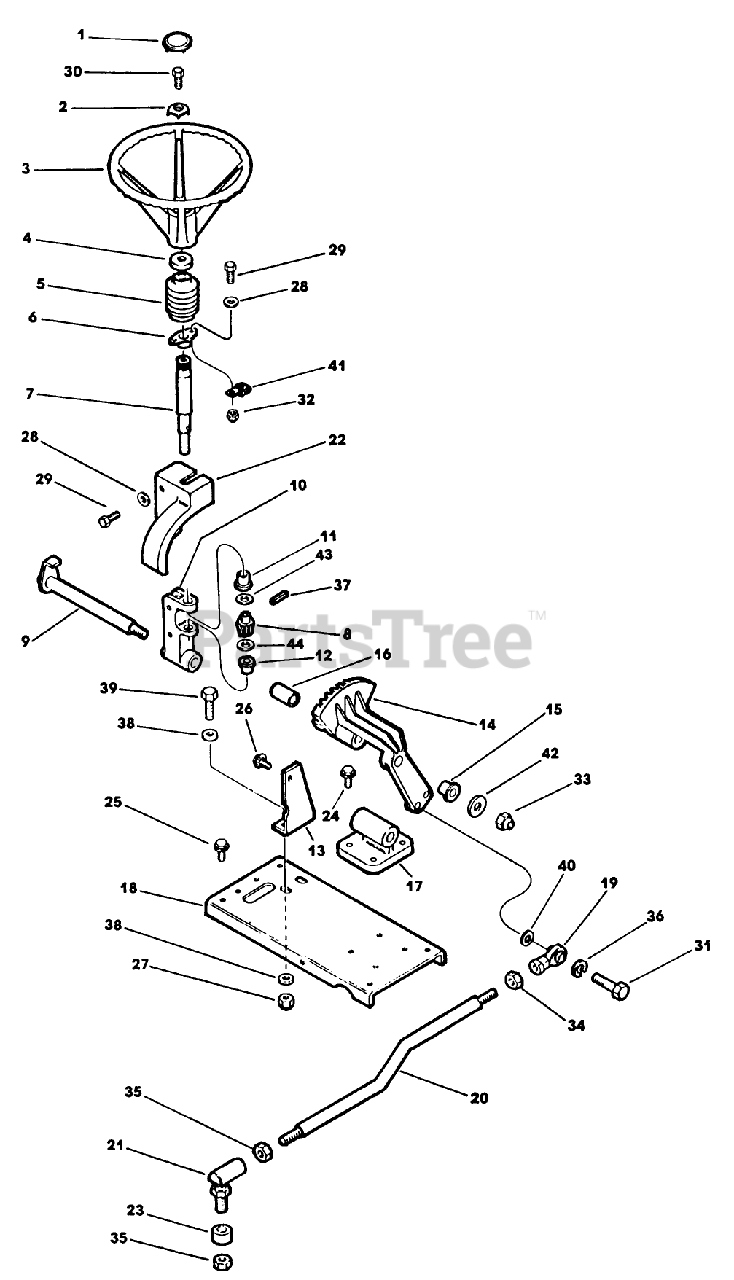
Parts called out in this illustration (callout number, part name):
1	CAP
6	BEARING AY.
8	GEAR - PINION
11	BUSHING
19	ROD END
21	BALL JOINT, RH
24	SCREW-THD ROLL, HWH
27	NUT-LOCKING
29	SCREW-HH
30	SCREW - HEX
32	NUT-LOCK, CONE
33	NUT-HEX
38	WASHER
41	CLAMP - J EX
43	WASHER
